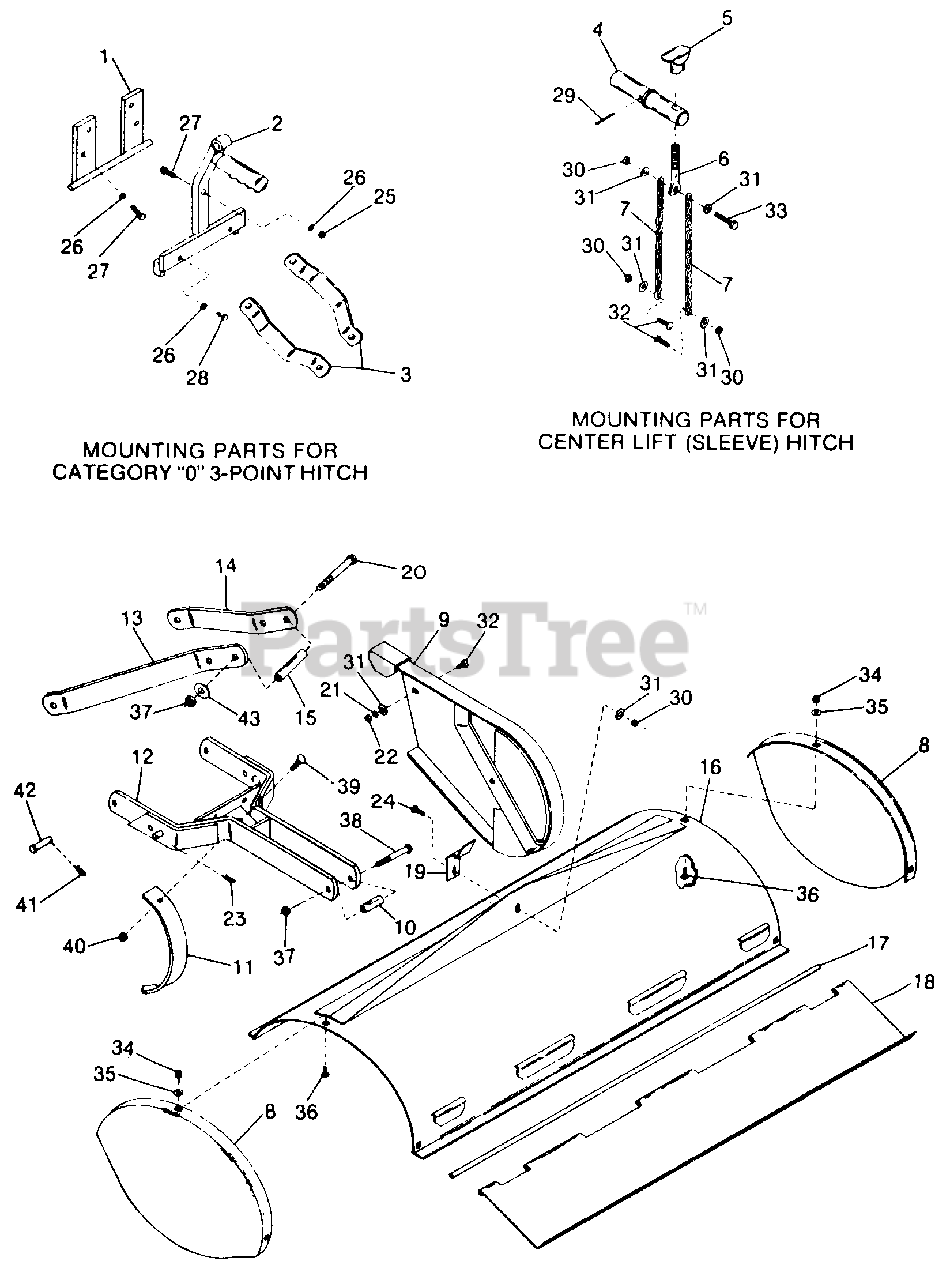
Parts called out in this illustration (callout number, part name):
1	Pin Assy, Latch
2	Bar Assy, Latch
4	Shaft Assy, Support
5	Tee Assy, Depth Control
6	Rod, Adjustment
7	Chain, Lift
9	Guard Assy, Belt
10	Bushing, Pivot
11	Plow, Spring Tooth
12	Bracket Assy, Lower Support
13	Bar, Support LH
14	Bar, Support RH
15	Spacer, 1/2 X 2-3/4 Pipe
16	Shield Assy, Safety
17	Rod, Pivot
18	Plate, Back
19	Clip, Retainer
20	Bolt, 1/2 X 4-3/4 Type 5
21	Washer, 5/16 Lock
22	Nut, 5/16 Type 5
23	Pin, Q.A. Cot
24	Bolt, 5/16 X 3/4 Crg Type 5
25	Nut, 3/8 Type 5
26	Washer, 3/8 Lock
27	Bolt, 3/8 X 1-1/2 Type 5
28	Bolt, 3/8 X 3/4 Type 5
29	Pin, 3/16 X 2 Cot
30	Nut, 5/16 Cad P/T Lock Type 5
31	Washer, .375 X .875 X .064
32	Bolt, 5/16 X 1 Crg Type 5
33	Bolt, 5/16 X 1-1/4 Type 5
34	Nut, 1/4 Cad P/T Lock Type 5
35	Washer, .266 X .625 X .036
36	Bolt, 1/4 X 1/2 Crg Type 1
37	Nut, 1/2 Lock
38	Bolt, 1/2 X 3-1/2 Type 5
39	Bolt, 3/8 X 1 Crg Type 5
40	Nut, 3/8 Cad P/T Lock Type 5
41	Pin, Q.A. Cot
42	Pin, Clevis
43	Washer, .562 X 1.375 X .086
